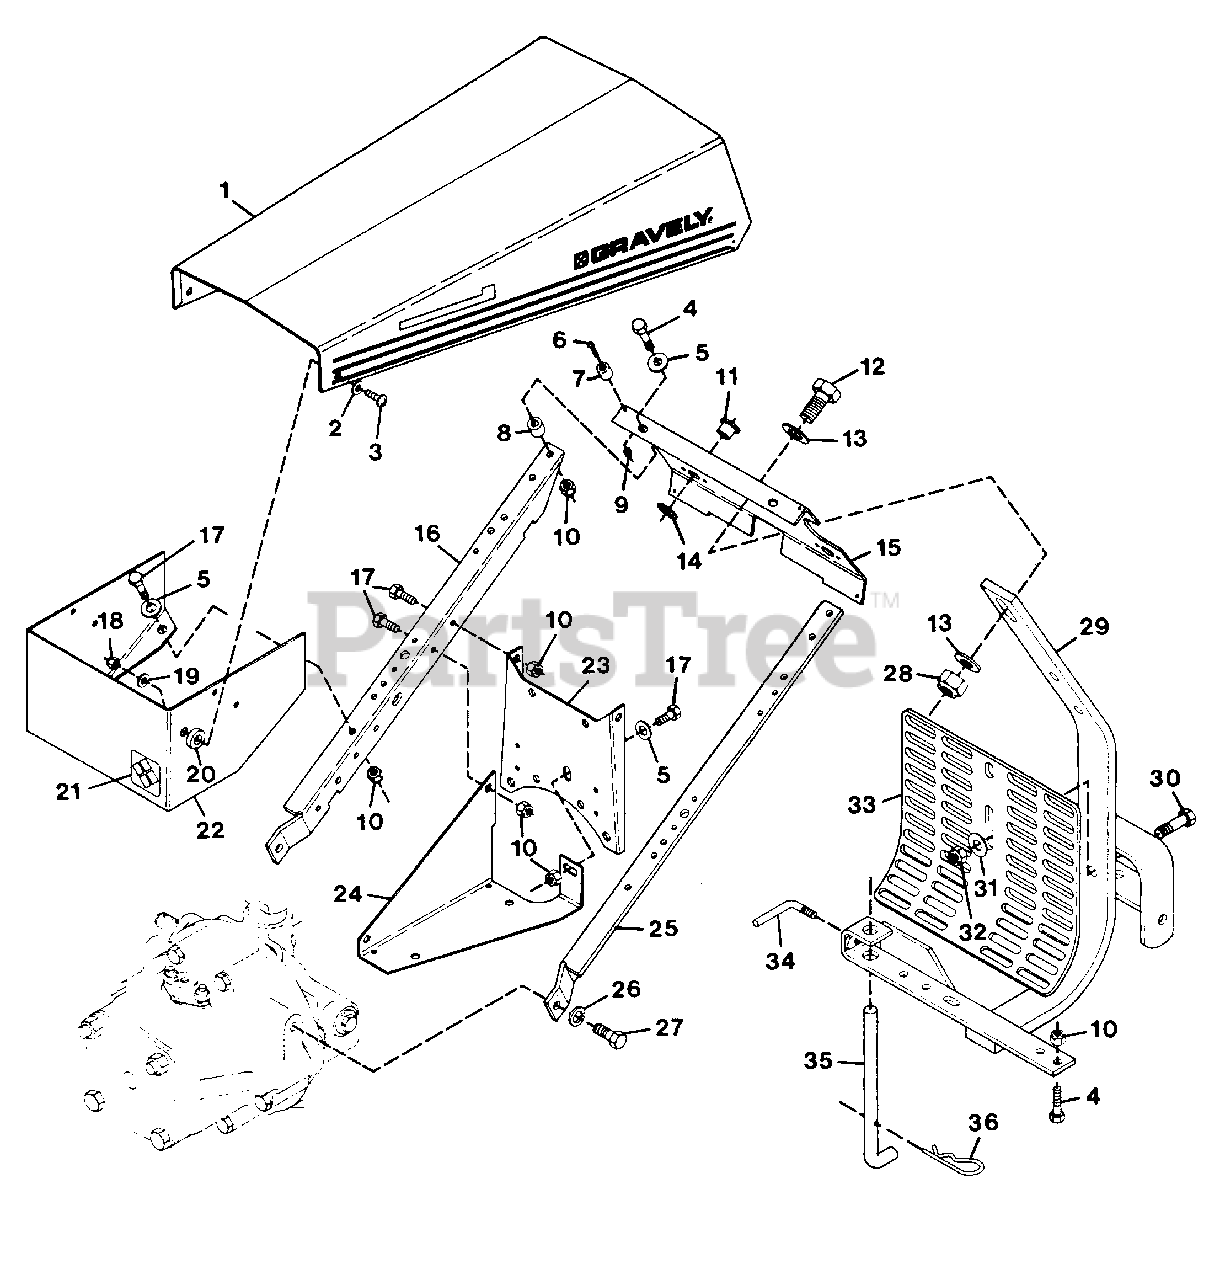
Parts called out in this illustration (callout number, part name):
1	ASSEMBLY, HOOD
2	WASHER, FLAT .281X.625X.065
3	SCREW, MACH. 1/4-20X1.00 PHD
4	BOLT, HEX 3/8-16X1.50
5	WASHER, FLAT .406X.812X.065
6	SCREW, MACH. 6-32X.625 PHD
7	BUMPER
8	BUSHING, REVERSE IDLER
9	NUT, MACH. LOCK 6-32
10	NUT, LOCK 3/8-16
11	BUSHING, .513X.750X.625
12	BOLT, HEX 5/8-11X2.00
13	WASHER, FLAT .656X1.250X1.00
14	RING, RETAINING
15	PLATE, SILK SCREEN
16	SUPPORT, HANDLEBAR R.H.
17	BOLT, HEX 3/8-16X.875
18	NUT, LOCK 1/4-20
19	WASHER, FLAT .313X.875X.065
20	BUSHING, HOOD
21	DECAL
22	SUPPORT, HOOD
23	BRACKET
24	TRAY, BATTERY
25	SUPPORT, HANDLEBAR L.H.
26	WASHER, LOCK 1/2 REG.
27	BOLT, HEX 1/2-13X1.00
28	NUT, LOCK 5/8-11
29	WELDMENT, HITCH 8 H.P.
30	BOLT, HEX 1/2-13X1.50
31	WASHER, FLAT .531X1.250X.100
32	NUT, LOCK 1/2-13
33	GUARD, ENGINE
34	HANDLE, ADJUSTING
35	STAND, KICK
36	PIN, HAIR
NS	DECAL, 8
NS	DECAL, SIDE STRIPE
NS	DECAL, GRAVELY
NS	DECAL, 6 LEAD
NS	DECAL, 8 LEAD
NS	DECAL, PROFESSIONAL
